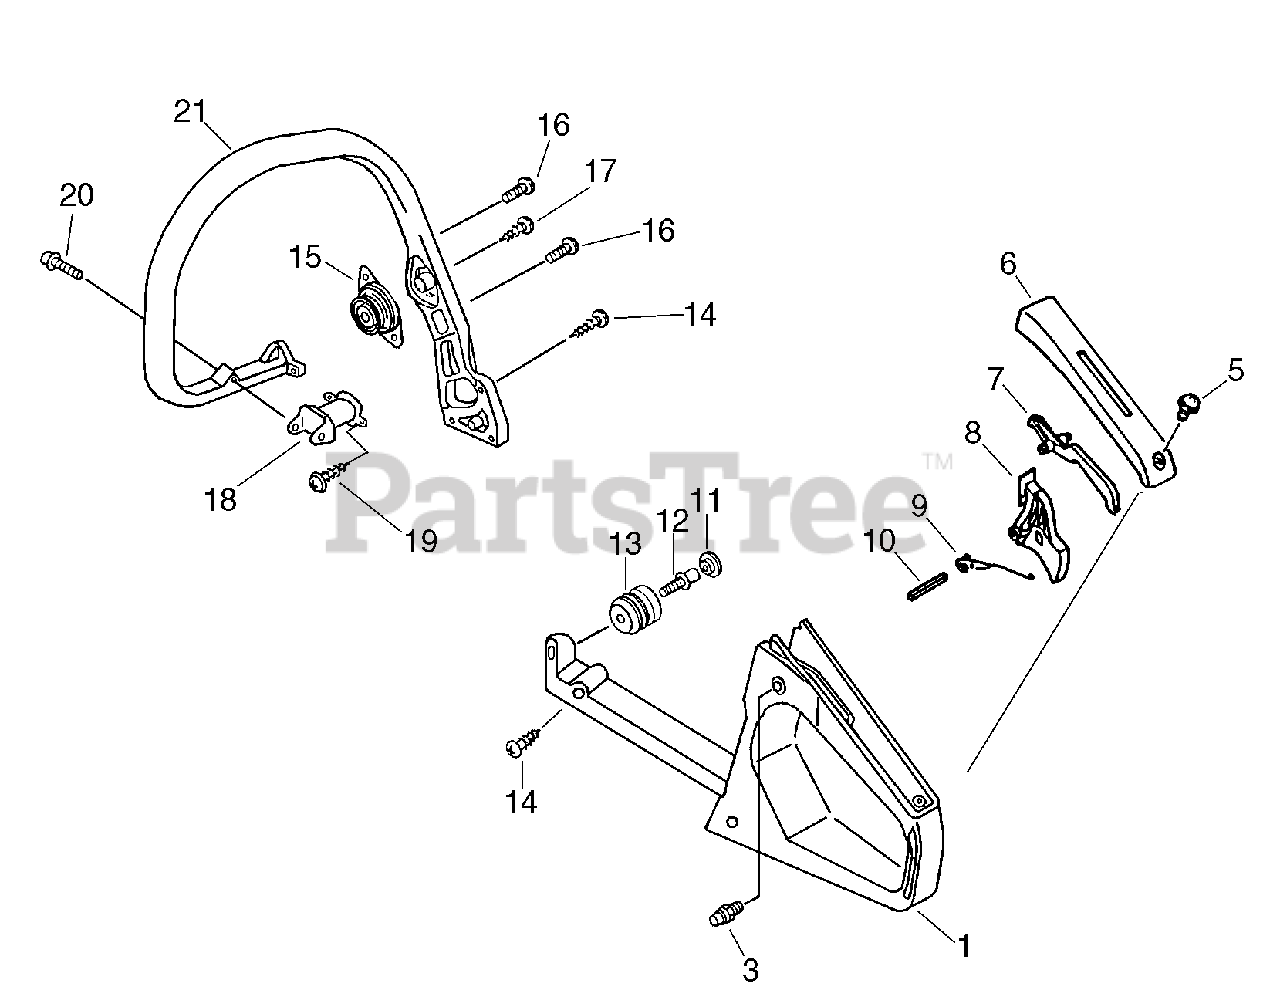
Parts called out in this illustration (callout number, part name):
1	HANDLE - REAR
3	LATCH, THROTTLE
5	SCREW - 4X12 -- TAPPING
6	COVER, HANDLE
7	LOCKOUT, THROTTLE
8	TRIGGER, THROTTLE
9	SPRING, TRIGGER
10	PIN - SPRING -- 4X30
11	CAP, CUSHION
14	SCREW - 5X20 -- TAPPING
16	SCREW - 4X16
17	SCREW - 5X16 -- TAPPING
19	SCREW - 4X12 -- TAPPING
20	SCREW - 4X22
21	HANDLE - FRONT
